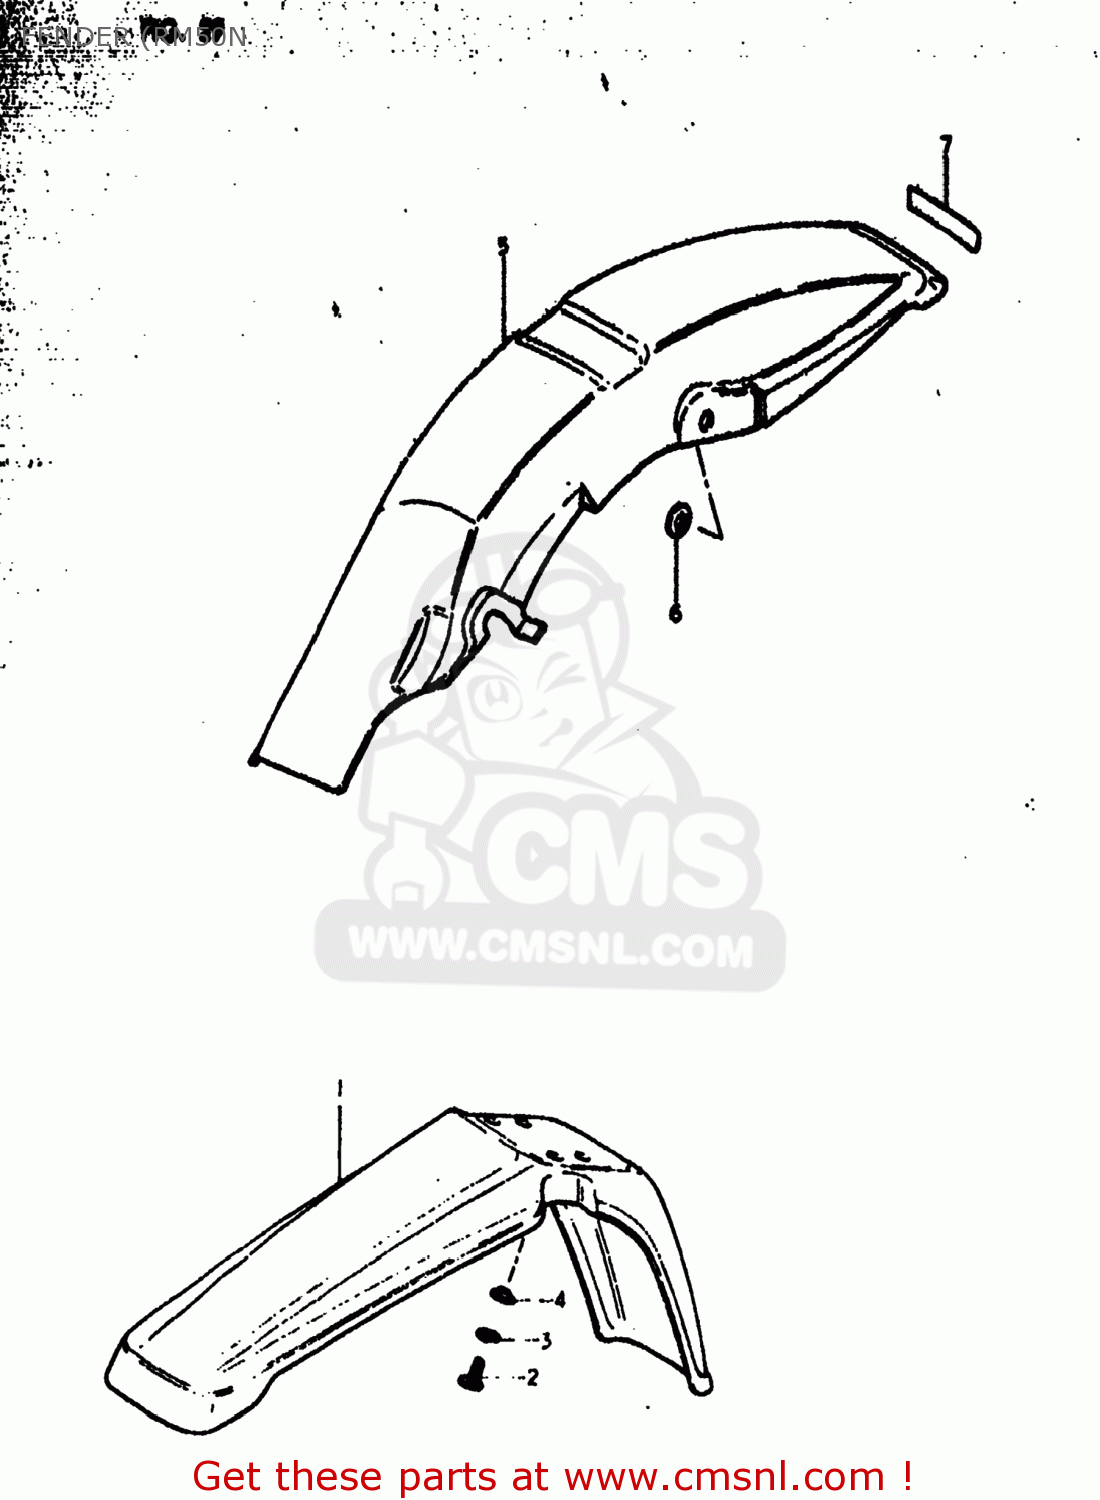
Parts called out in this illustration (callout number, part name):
1	FENDER,FRONT
2	BOLT, UPPER
3	LOCK WASHER
4	SPACER
5	FENDER,REAR
6	WASHER
7	EMBLEM,FRONT FENDER
